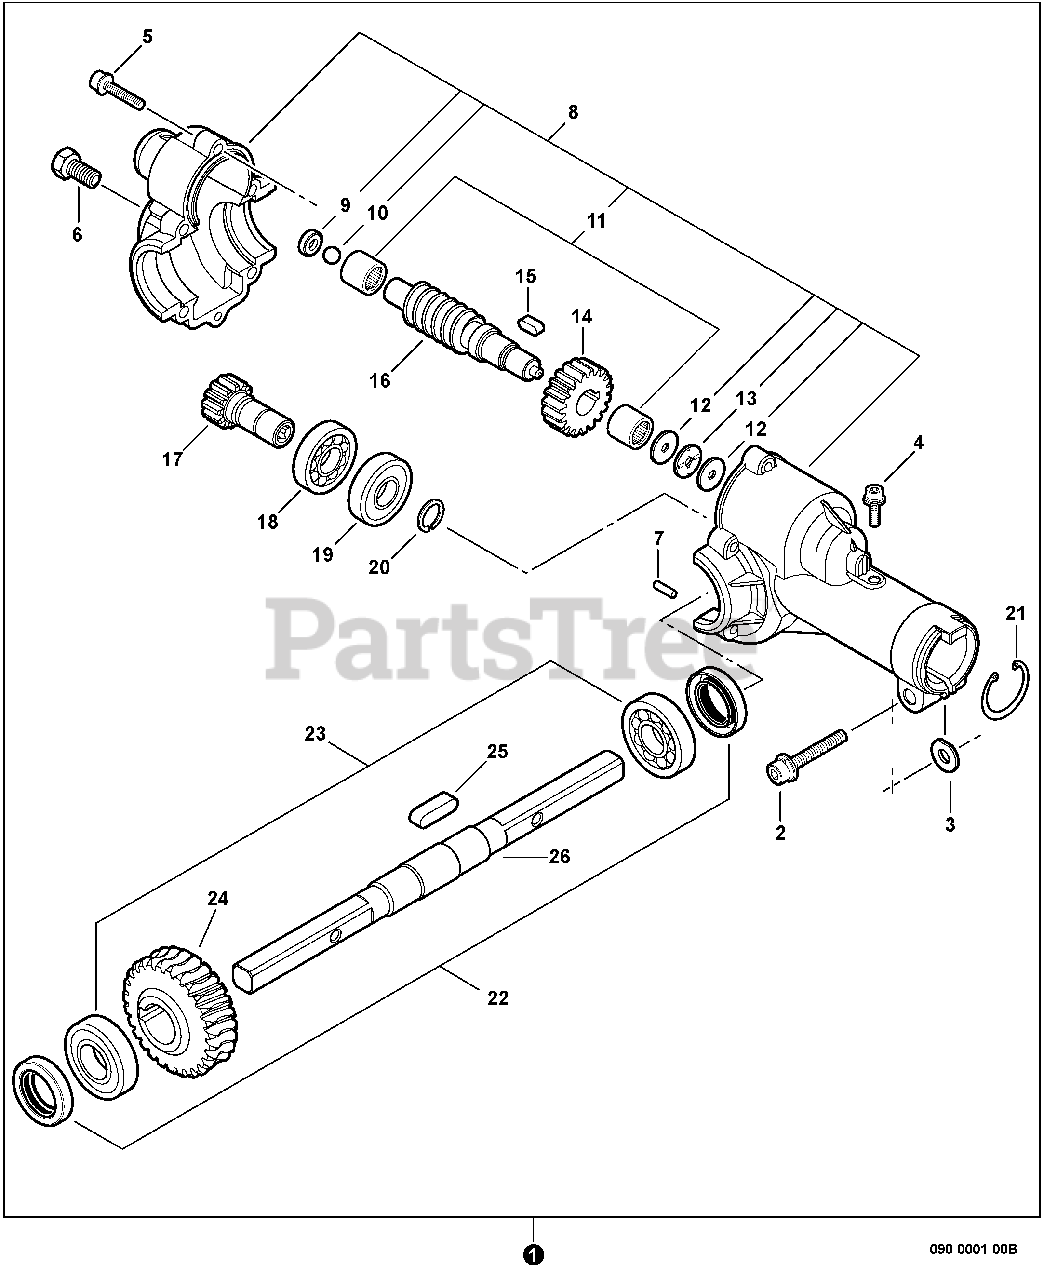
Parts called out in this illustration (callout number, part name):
1	GEAR CASE ASSY
2	SCREW - 6X30
4	SCREW - 5X12
5	SCREW - 5X20
6	BOLT - 8X10
7	PIN - LOCATING
8	GEAR CASE ASSY
9	BUSHING
11	BEARING, NEEDLE
13	BEARING, THRUST
14	GEAR - SPUR
16	GEAR - WORM
17	GEAR - SPUR
18	BEARING, BALL - 6901
19	BEARING, BALL - 6901
20	RING, RETAINING - 12
21	RING, RETAINING - 24
22	SEAL, OIL - 17
23	BEARING, BALL - 6003
24	WHEEL, WORM
26	GEAR - SHAFT
